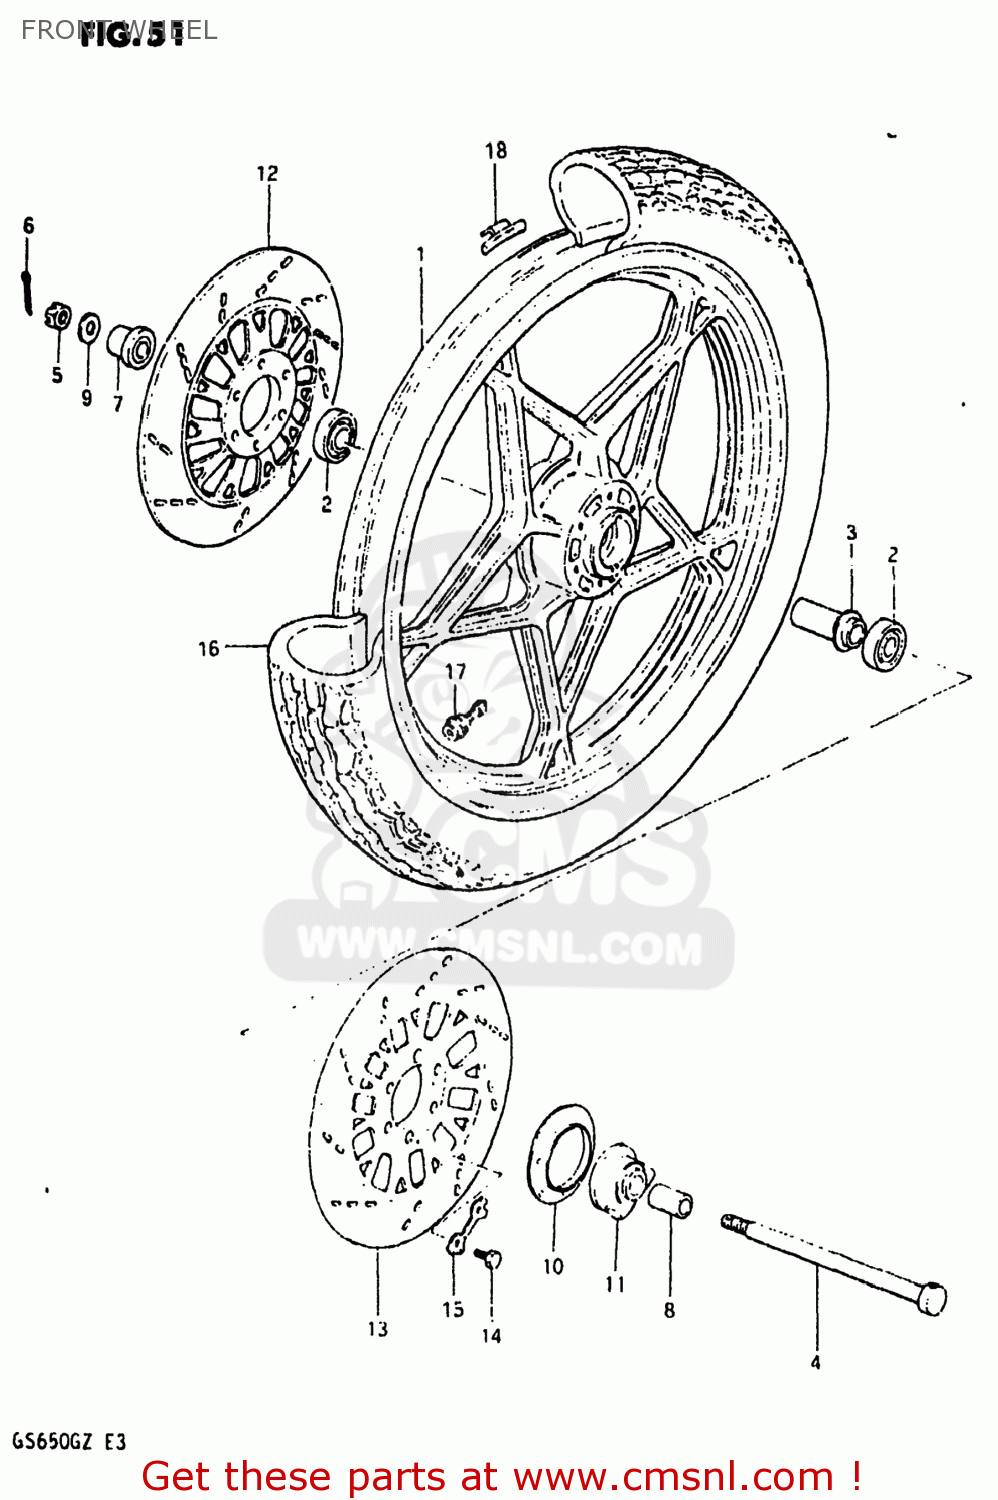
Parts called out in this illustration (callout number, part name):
1	CASTING WHEEL,FRONT 1.85
2	BEARING
3	SPACER,FR HUB BEARING
4	AXLE,FRONT
5	NUT 12MM
6	COTTER PIN
7	SPACER,FR HUB BEARING,R
8	SPACER(15X22X30)
9	WASHER
10	DUST SEAL,SPEEDOMETER GEAR BOX
11	BOX ASSEMBLY,SPEEDOMETER GEAR
12	DISC,FR BRAKE,R
13	DISC,FR BRAKE,L
14	BOLT(8X25)
15	WASHER
16	TIRE,FRONT
17	VALVE ASSEMBLY,WHEEL RIM,J
18	BALANCER,WHEEL
